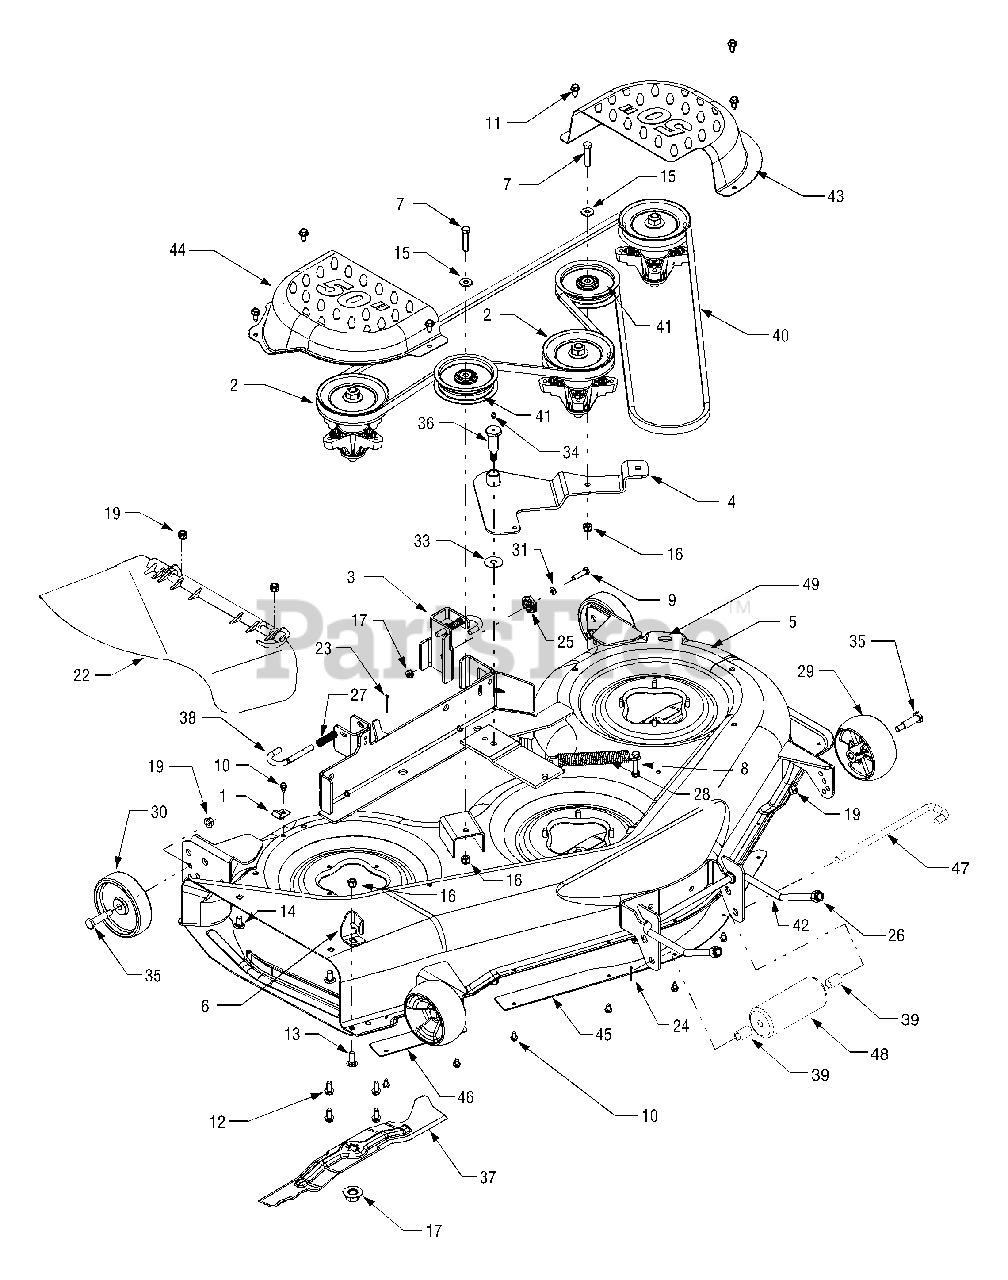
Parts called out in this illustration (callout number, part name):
1	Hook, Retainer
2	Spindle Assembly
7	Screw, 3/8-16, 1.75
8	Screw, 5/16-18 x 2.00
9	Screw, 5/16-18, 1.25, Gr5
10	Screw, 1/4-20 x 0.5
11	Screw, 5/16-18 x.625
12	Screw, 5/16-18 x.75
13	Screw, Carriage, 3/8-16 x 1.0
14	Screw, Carriage, 3/8-16 x.75
15	Washer, Flat,.406 x.875 x.059
16	Nut, Nylon Lock, 3/8-16
17	Nut, Hex, Flange, 5/8-18
18	Nut, Nylon Lock, 5/16-18
19	Nut, Flange Lock, 3/8-16
20	Nut, Hex, 5/16-18, Gr5
21	Nut, 7/16-14
22	Chute Assembly, Side Discharge
23	Pin, Cotter, 1/8 x 1.25
24	Pin, Cotter, 3/32 x 1.25
25	Deck Adjustment Gear
26	Lock Nut, Hex, 1/2-13, Nylon
27	Spring, Compression,.531 x 1.75
28	Spring, Extension,.94 x 6.74
29	Deck Wheel, 5.0
30	Deck Wheel, 5.0
31	Washer, Lock, 5/16, Regular Duty
32	Washer, Bell,.45 x 1.0 x.062
33	Washer, Flat,.442 x 1.38 x.060
34	Fitting, Lube, 3/16
35	Shoulder Screw
36	Screw, Shoulder,.68 x 1.59
37	Blade
38	Rod, Handle, Deck Release.375 Via
39	Spacer,.550 x.755 x 1.1
40	Belt, V-Type, Aramid
41	Pulley, Idler, 3.5"
42	Rod, Deck Adjustment
47	Roller Pin, 5"
48	Front Roller
